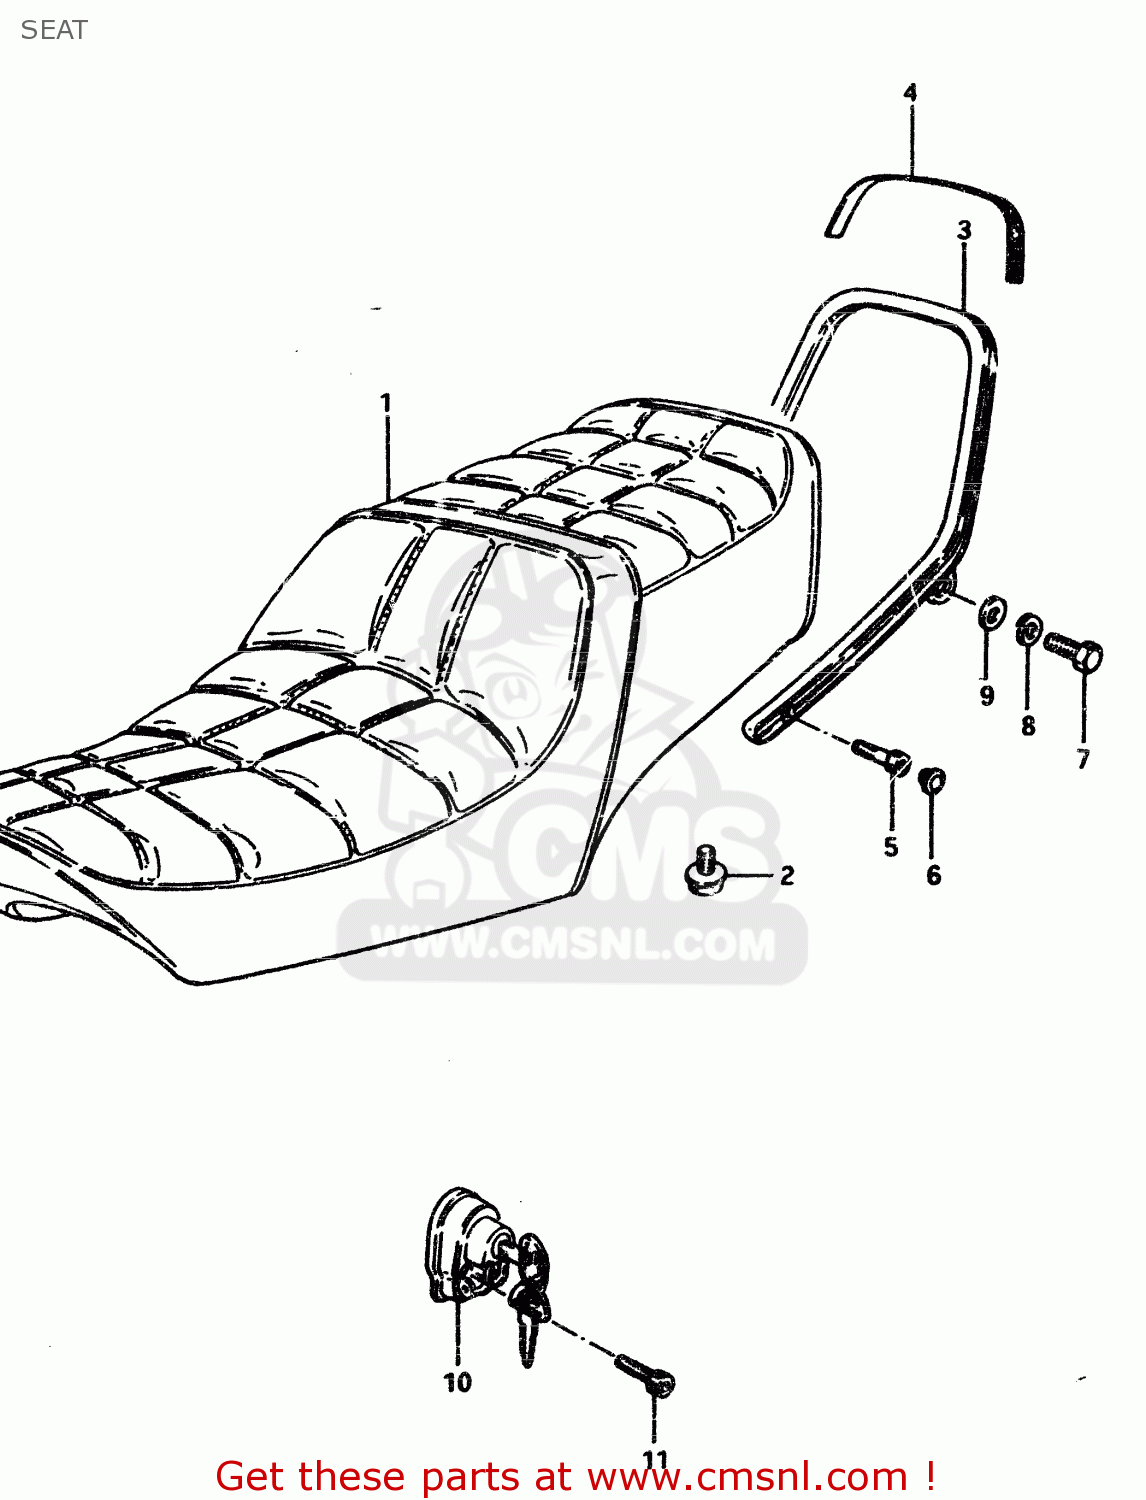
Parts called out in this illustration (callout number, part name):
1	SEAT ASSY
2	BOLT
3	HANDLE,PILLION RIDER
4	RUBBER,PILLION RIDER HANDLE
5	BOLT
6	CAP(OD:14.5)
7	BOLT
8	LOCK WASHER
9	WASHER
10	LOCK ASSY,HELMET
11	BOLT 5X25
